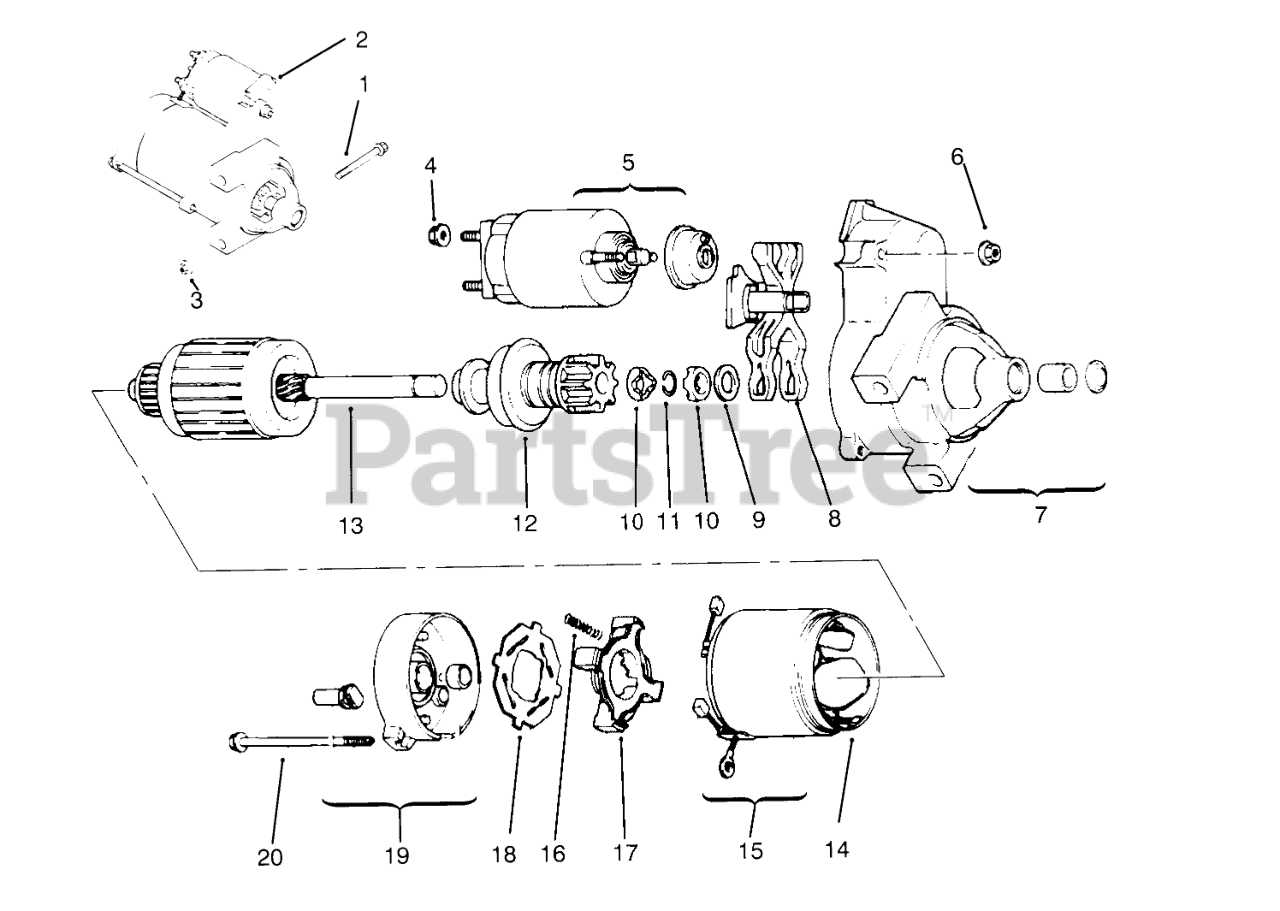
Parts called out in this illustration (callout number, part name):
1	Screw M8x1.25x80 (Only On: 72103)
2	Starter INCL 4-20 (Only On: 72103)
3	Nut M8x1.25 (Only On: 72103)
4	Nut-Starter (Only On: 72103)
5	Solenoid (Only On: 72103)
6	Nut Starter (Only On: 72103)
7	Cap-Drive End (Only On: 72103)
8	Lever Starter Drive (Only On: 72103)
9	Washer-Thrust (Only On: 72103)
10	Nut-Stop Collar (Only On: 72103)
11	Ring-Retainer (Only On: 72103)
12	Drive-Pinion (Only On: 72103)
13	Armature-Starter (Only On: 72103)
14	Frame (Only On: 72103)
15	Kit-Brush INCL 16 (Only On: 72103)
16	Spring-Brush (Only On: 72103)
17	Holder-Brush (Only On: 72103)
18	Insulator (Only On: 72103)
19	Cap-Commutator End (Only On: 72103)
20	Bolt (Only On: 72103)
